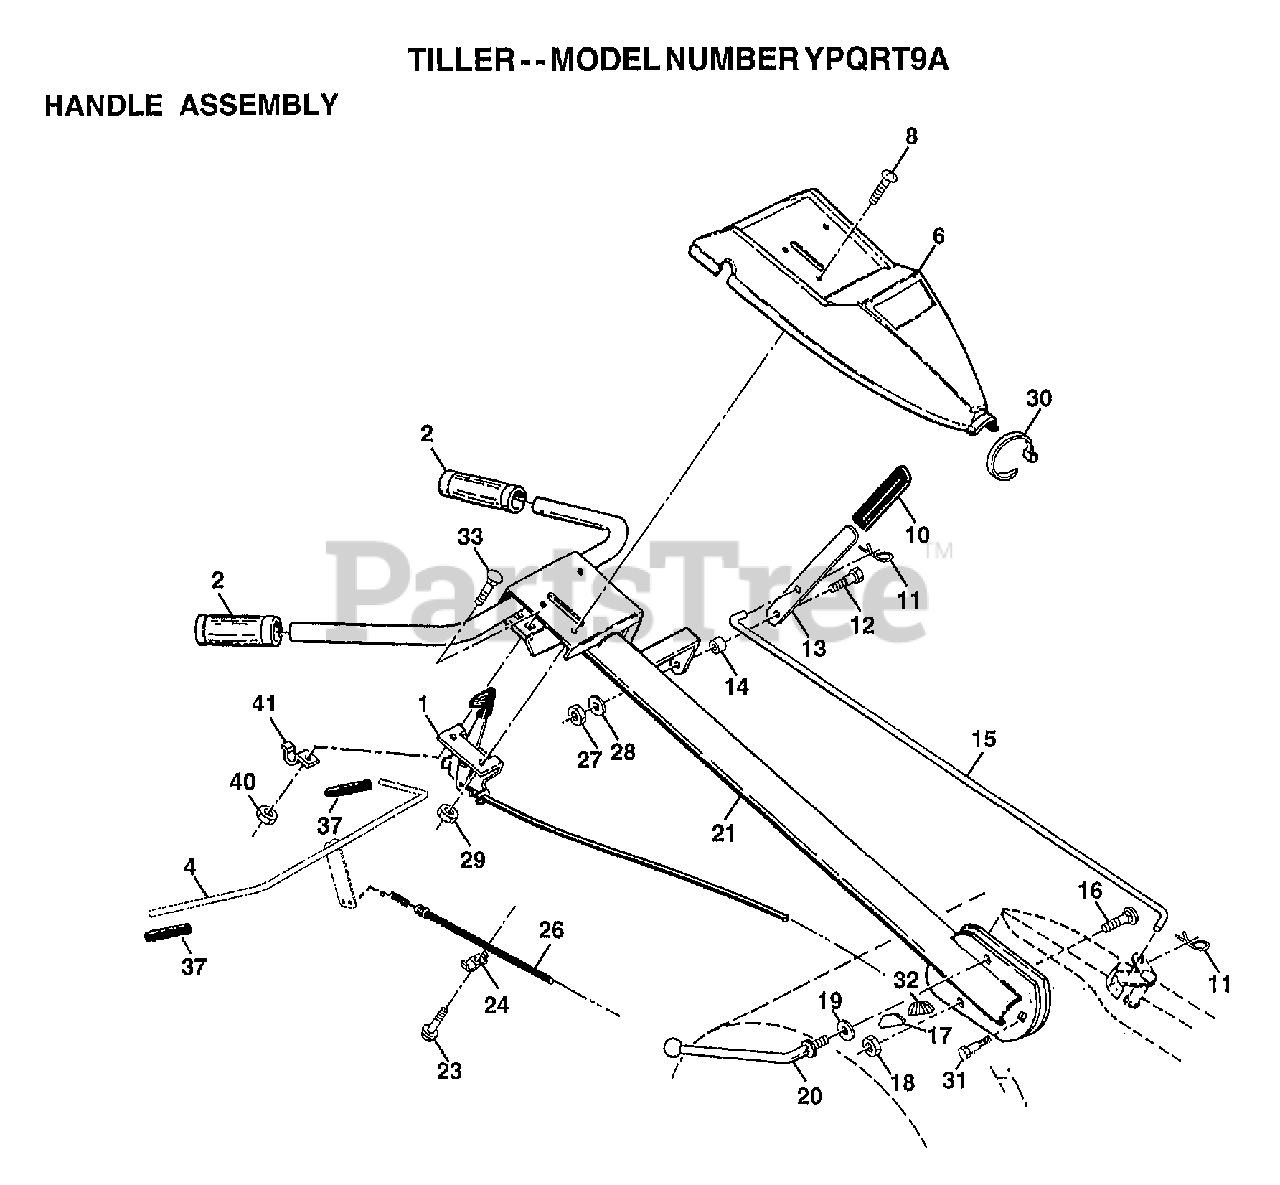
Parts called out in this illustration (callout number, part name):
1	CONTROL.THROTTLE
4	BAR ASM CONTROL
6	"PANEL,CONT TI"
8	SCREW.PNHD.10-24
10	GRIP T
11	RETAINER M
12	SHOULDER BOLT ST
13	SHIFT HANDLE CRT
14	GROMMET CRT
15	ROD.SHIFT
16	BOLT D
17	LOCK CRT
18	LOCKNUT
19	WASHER CRT
20	LEVER LOCK CRT
24	CONDIUT CLIP T
26	CABLE.CLUTCH
28	LOCKWASHER
30	TIE CABLE CRT
31	BOLT PIVOT
32	LOCK.HANDLE
33	BOLT
37	GRIP BAR CRT
40	NUT
